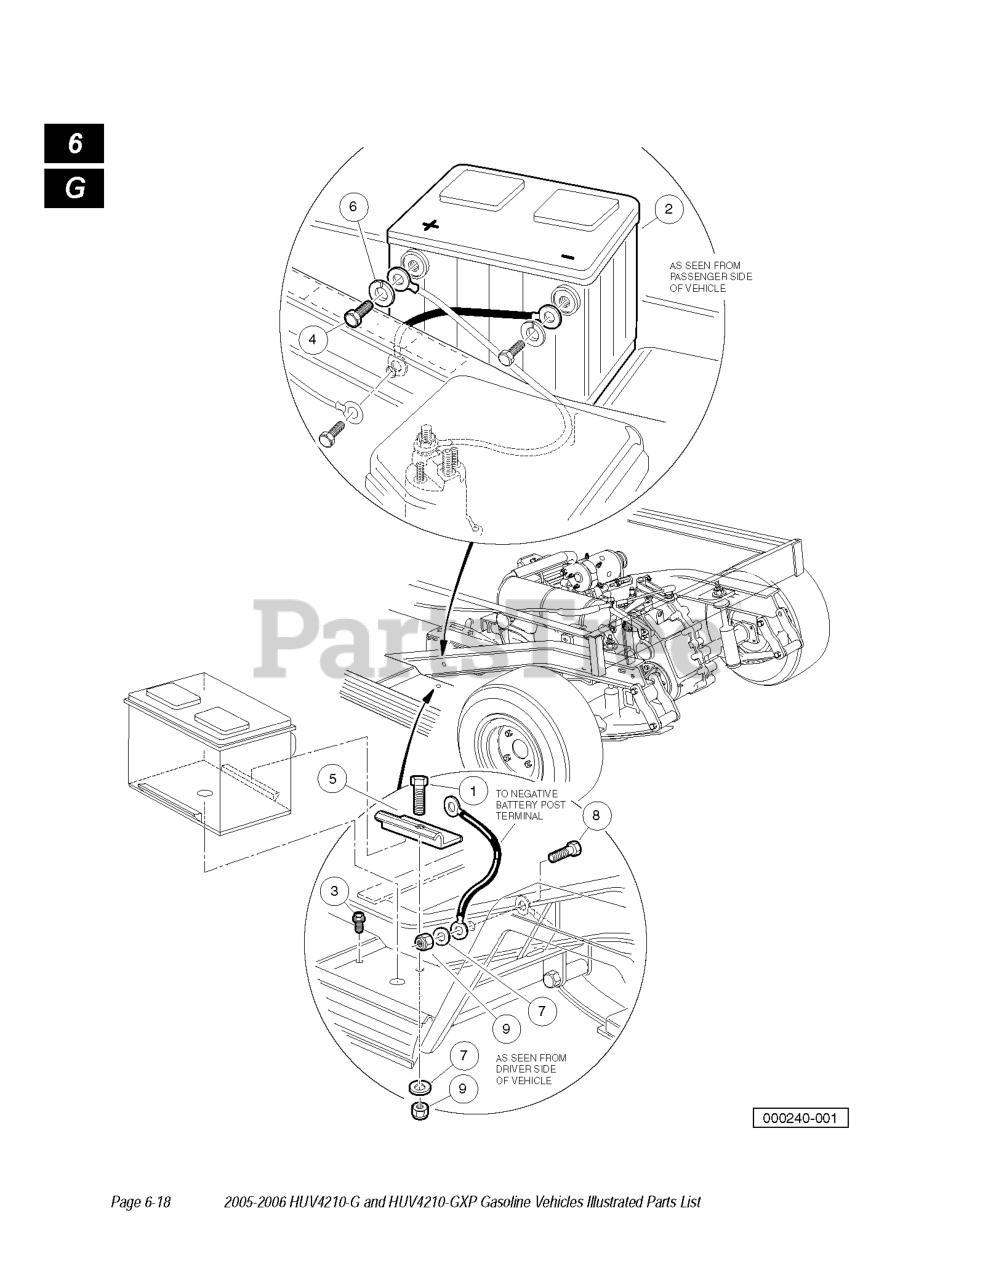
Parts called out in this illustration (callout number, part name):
1	SCREW HEX CAP
2	BATTERY, 12 VOLT
5	CLAMP - BATTERY
6	LOCKWASHER, 3/8 STAINLESS STL
7	WASHER, 5/16 TYPE A FLAT
8	SCREW, 5/16-18 X .75 HX HD CAP
9	LOCKNUT, 5/16-18 NYLON INSERT
